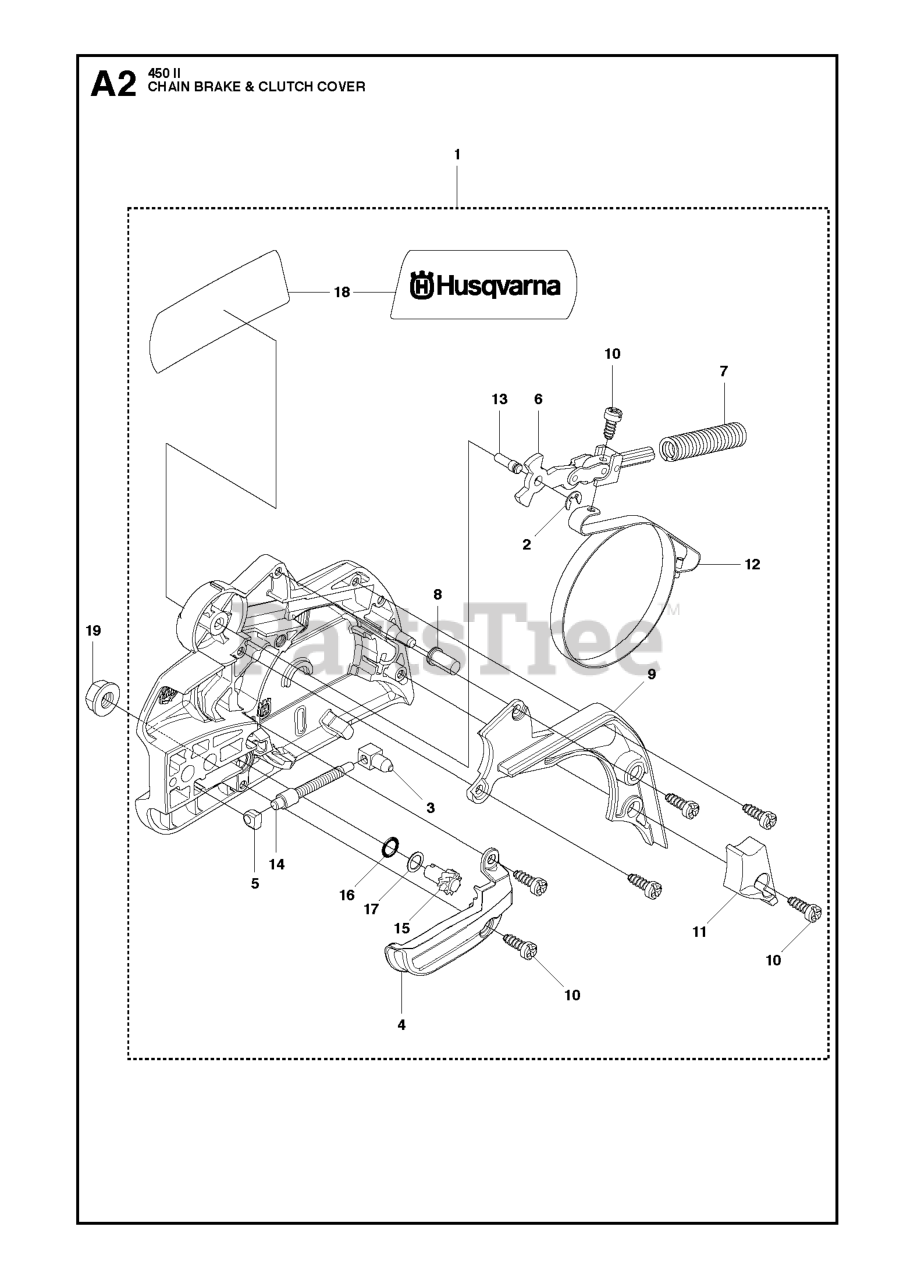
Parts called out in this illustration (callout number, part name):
1	CLUTCH COVER
4	CHAIN GUIDE
9	COVER, CHAIN BRAKE
11	WEAR GUARD, CHAIN
12	BRAKE BAND
15	WORM WHEEL
18	LABEL 400 SERIES
19	NUT M8 FLANGE
